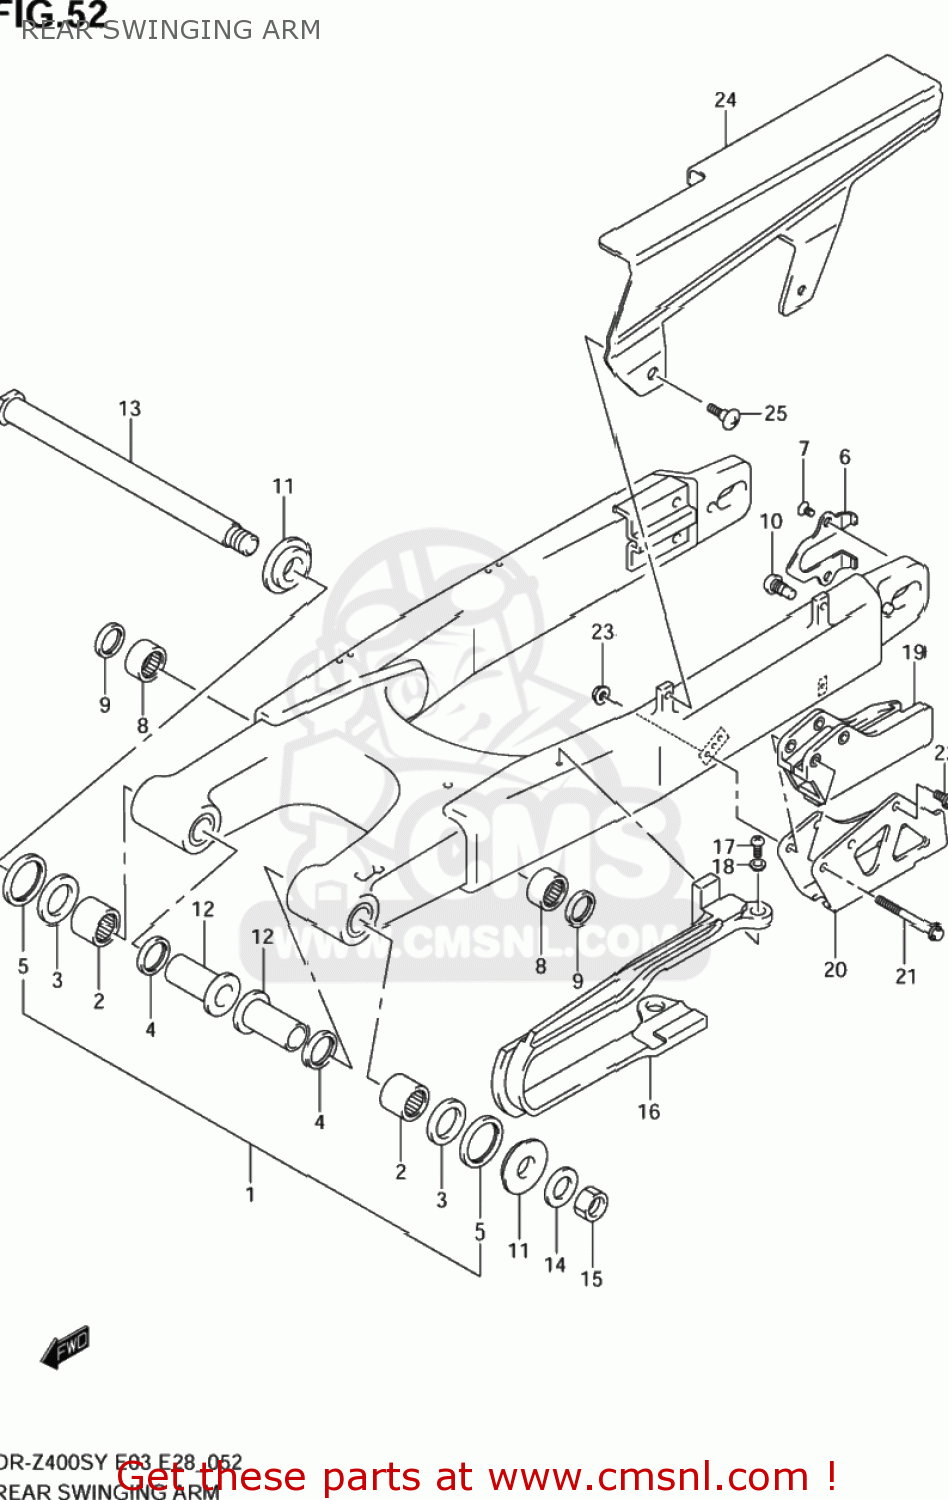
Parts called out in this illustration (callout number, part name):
1	SWING ARM ASSEMBLY,REAR
2	BEARING(22X29X30)
3	BEARING(22X35X2)
4	SEAL,OIL(22X29X4)
5	SEAL,RR SWGARM PIVOT OUTER
6	PLATE,RR SWING ARM AXLE
7	SCREW(5X8)
8	BEARING(20X27X15)
9	SEAL,CUSHION LEVER DUST
10	STOPPER,CHAIN ADJUSTER
11	SPACER,SWINGINGARM PIVOT OUTER
12	SPACER,SWGARM PIVOT INNER
13	SHAFT,RR SWINGINGARM PIVOT
14	WASHER, FIXED DRIVE FACE
15	NUT
16	BUFFER,CHAIN TOUCH DEFENSE
17	SCREW
18	WASHER
19	GUIDE,CHAIN
20	PLATE,CHAIN GUIDE
21	BOLT
22	BOLT
23	NUT
24	CASE,CHAIN
25	SCREW(6X16)
